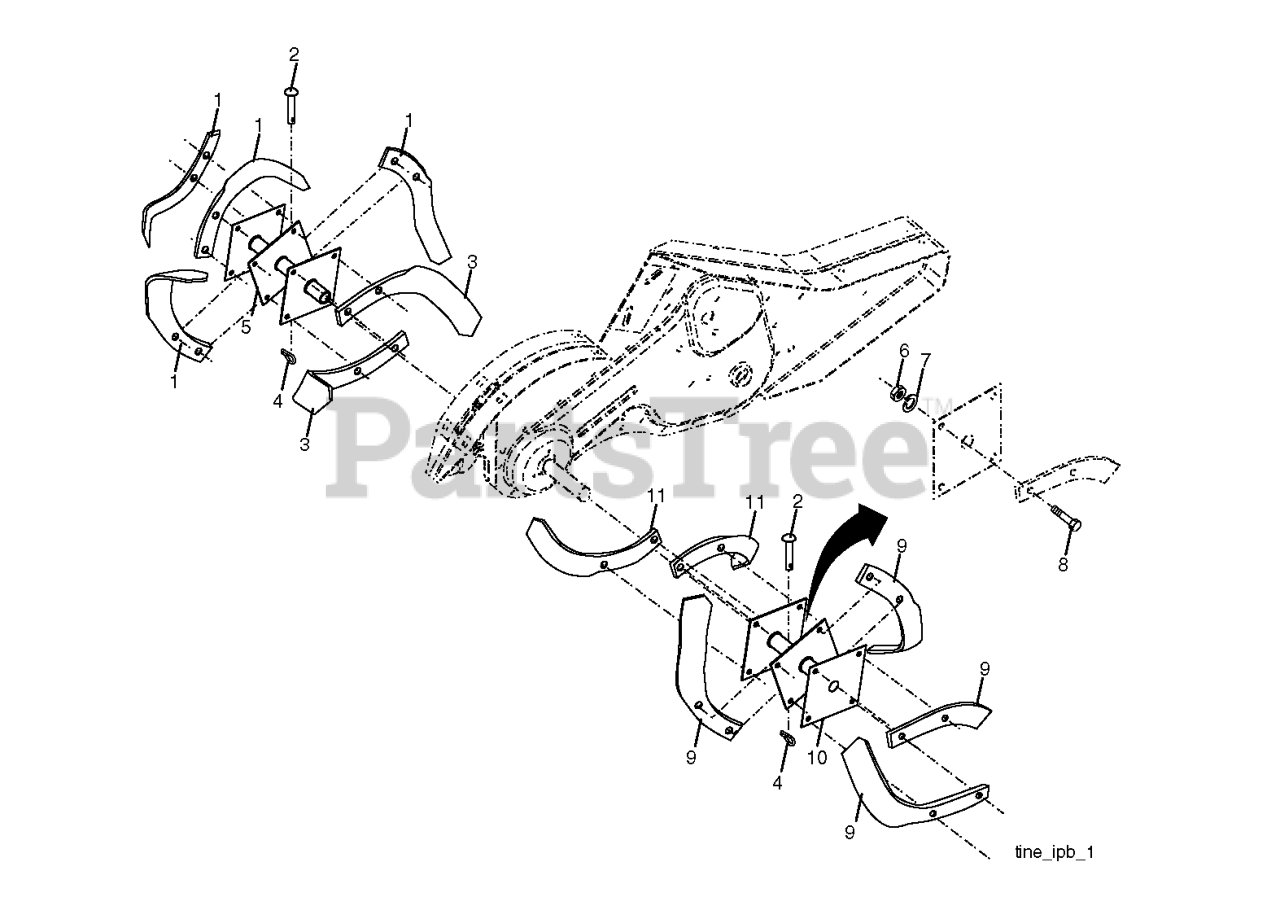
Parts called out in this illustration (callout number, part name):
1	TINE TI
2	PIN RETAINING SCREW
3	TINE.LH.12"(72L)
4	SPRING RETAINER
5	HUB.&.PLATE.ASM.LH
6	NUT
7	WASHER, LOCK 3/8
8	BOLT.HEX.001X20.37-24X1.ZINC
9	TINE TI
10	HUB & PLATE ASM RH
11	TINE.RH.12"(72R)
